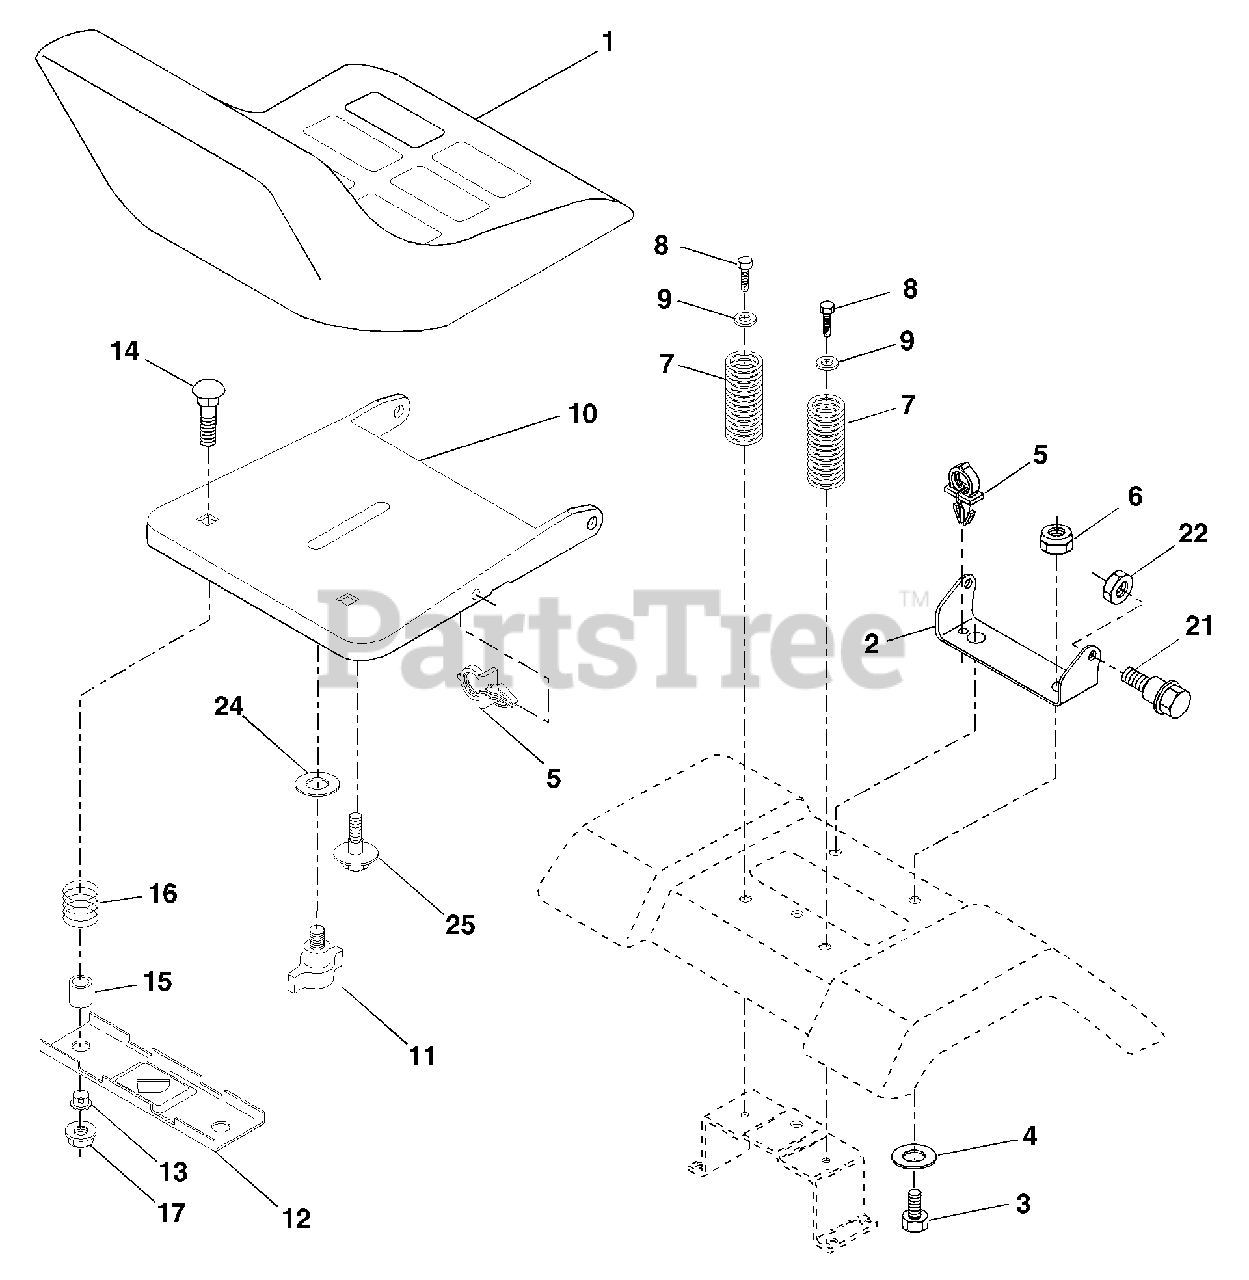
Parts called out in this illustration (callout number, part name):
1	Seat
2	Bracket Pivot Seat 8 720
3	Bolt Fin Hex 3/8-16unc X 1
4	Washer 13/32 X 1 X 10 Ga
5	Clip Push-In
6	Nut Hex w/Ins. 3/8-16 Unc
7	Spring Seat Cprsn 2 250 Blk Zi
8	Screw 3/8-16 X 1
9	Washer 13/32 X 1 X 14 Ga.
10	Pan Seat
11	Knob Seat Adj Wingnut
12	Bracket Mounting Switch
13	Bushing Snap Blk Nyl 50 Id
14	Bolt Rdhd Sqnk 1/4-20x1-1/2
15	Spacer Split 28x 96 Yel Zinc
16	Spring Cprsn 1 27 Blk Pnt
17	Nut Lock 1/4 Lge Flg Gr 5 Zinc
21	Bolt Shoulder 5/16-18 Unc
22	Nut Hex Lock W/Ins 5/16-18
24	Washer 17/32 X 1-3/16 X 12 Ga.
25	Bolt Shoulder 5/16-18 X 62
